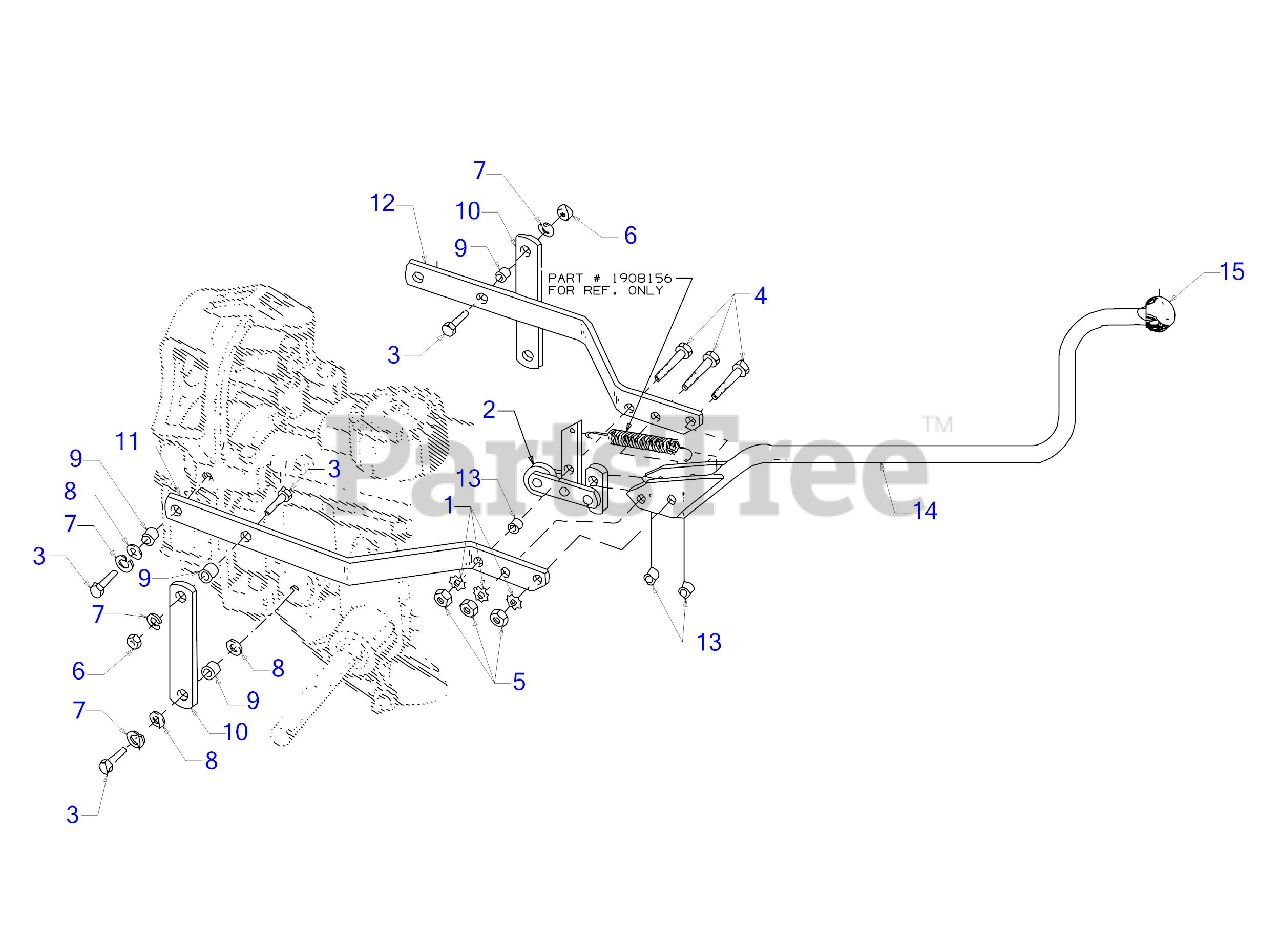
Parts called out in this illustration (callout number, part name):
1	WASHER-EXTERN L
3	SCREW 3/8-16 x 1 GR5
4	SCREW 5/16-18 x 1.50 GR5
5	HEX NUT
6	HEX NUT
7	LOCK WASHER 3/8
8	FLAT WASHER
9	BUSHING .5 X
10	BAR-CLUTCH YOK
11	YOKE (LH) RED
13	BUSHING .5 x .316 x .375
14	FORWARD/REVERSE LEVER ASSEMBLY
15	KNOB W/INLAY-F
